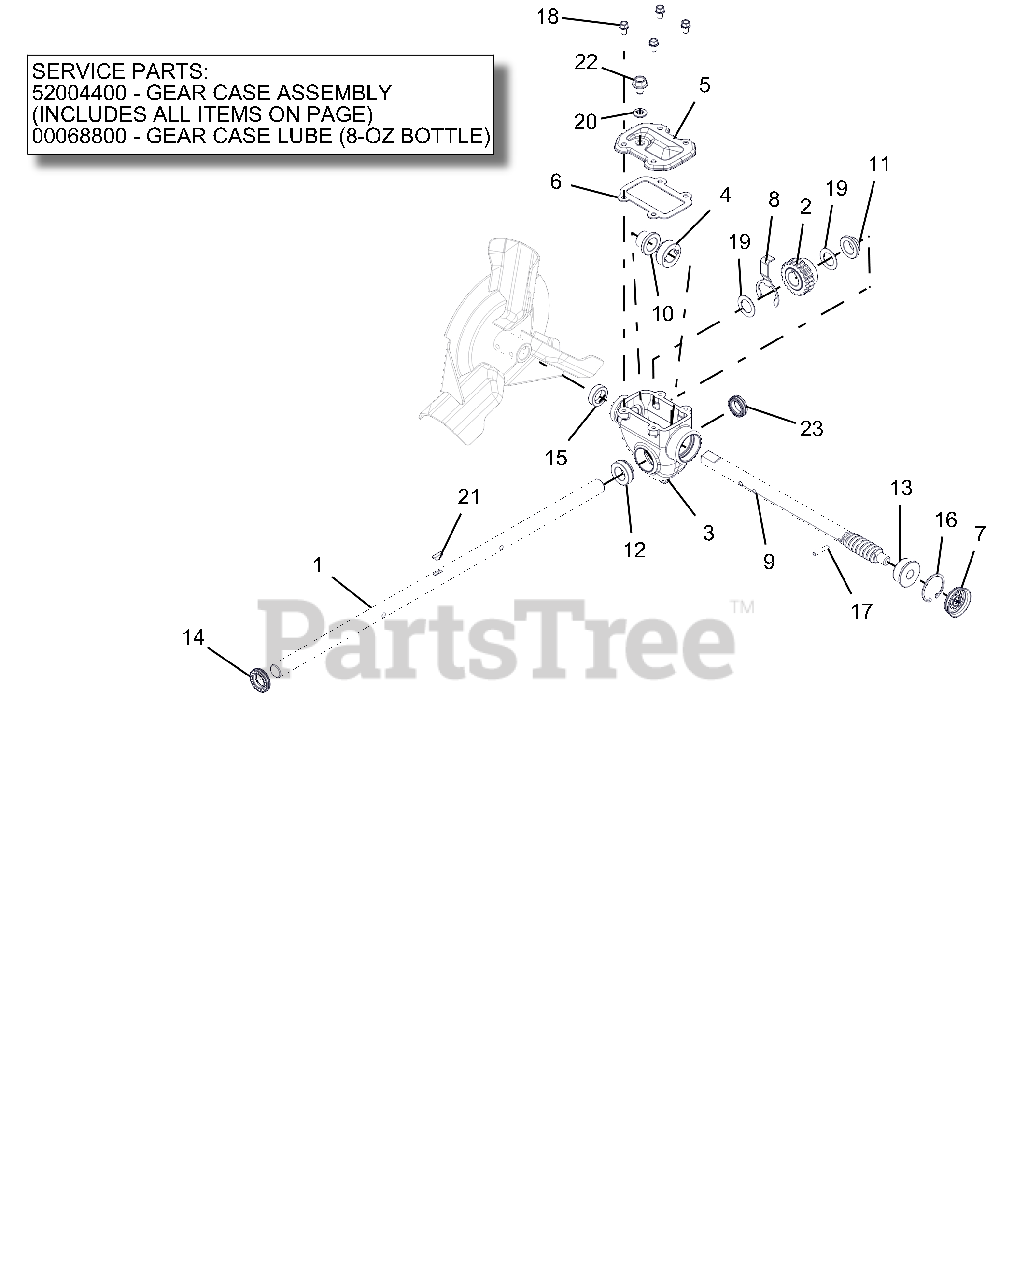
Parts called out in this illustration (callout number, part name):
1	SHAFT, RAKE - 24" (.750 DIA)
2	WORM GEAR
3	GEARCASE, COMPACT MACHINED
4	THRUST COLLAR, .75" ID SLIPFIT
5	COVER, TOP - COMPACT
6	GASKET, TOP - COMPACT GEARCASE
7	COVER, GEAR CASE 1.50"
8	BUSHING RETAINER, COMPACT
9	SHAFT, WORM - COMPACT
10	BSHG-FLG .755X.878X.75X1.25
11	BSHG-FLG .755X.878X.424X1.25
12	BSHG-FLG COMPACT, RIGHT
13	BSHG-FLG .503X1.303X.62X1.465
14	SEAL-OIL .748X1.300X.250 TBC29
15	SEAL-OIL .748X1.125X.312 TB2-H
16	RG-RTNG-INT 1.500X.050
17	PIN-STR .188X1.00 6150
18	BOLT, SEMS .25-20X.50 GR5 YWZC
19	WSHR-FL-STL .760X1.225X.032 YZ
20	WSHR-BND-SEAL .38X.75X.11 GALV
21	KEY-WDRF .19X.63 HRD #61
22	@SCR-ROLOK .38-16X.50 HWH YWZC
23	SEAL-OIL .748X1.125X.312 TBC29
24	GEAR CASE, 24" IRON SM TOP-LD
25	ARIENS L3 LUBE, 8 OZ BOTTLE
